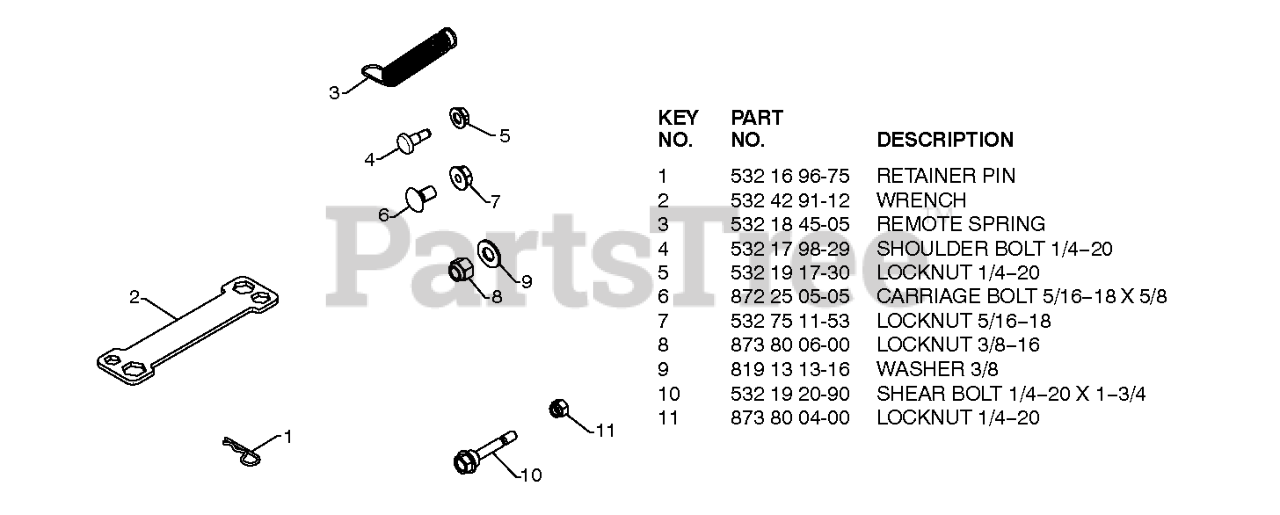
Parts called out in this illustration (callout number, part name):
1	SPRING RETAINER
2	WRENCH.SNOWTHROWER.ZINC.YZ
3	SPRING.DEFLECTOR.REM.CHUTE
4	BOLT, SHOULDER
5	NUT.HEX.FLANGE.1/4
6	BOLT
7	NUT.LOCK.5/16-18
8	NUT
9	WASHER
10	BOLT.SHOULDER.SHEAR.1/4-20.
11	LOCKNUT.NYLOC.1/4-20
